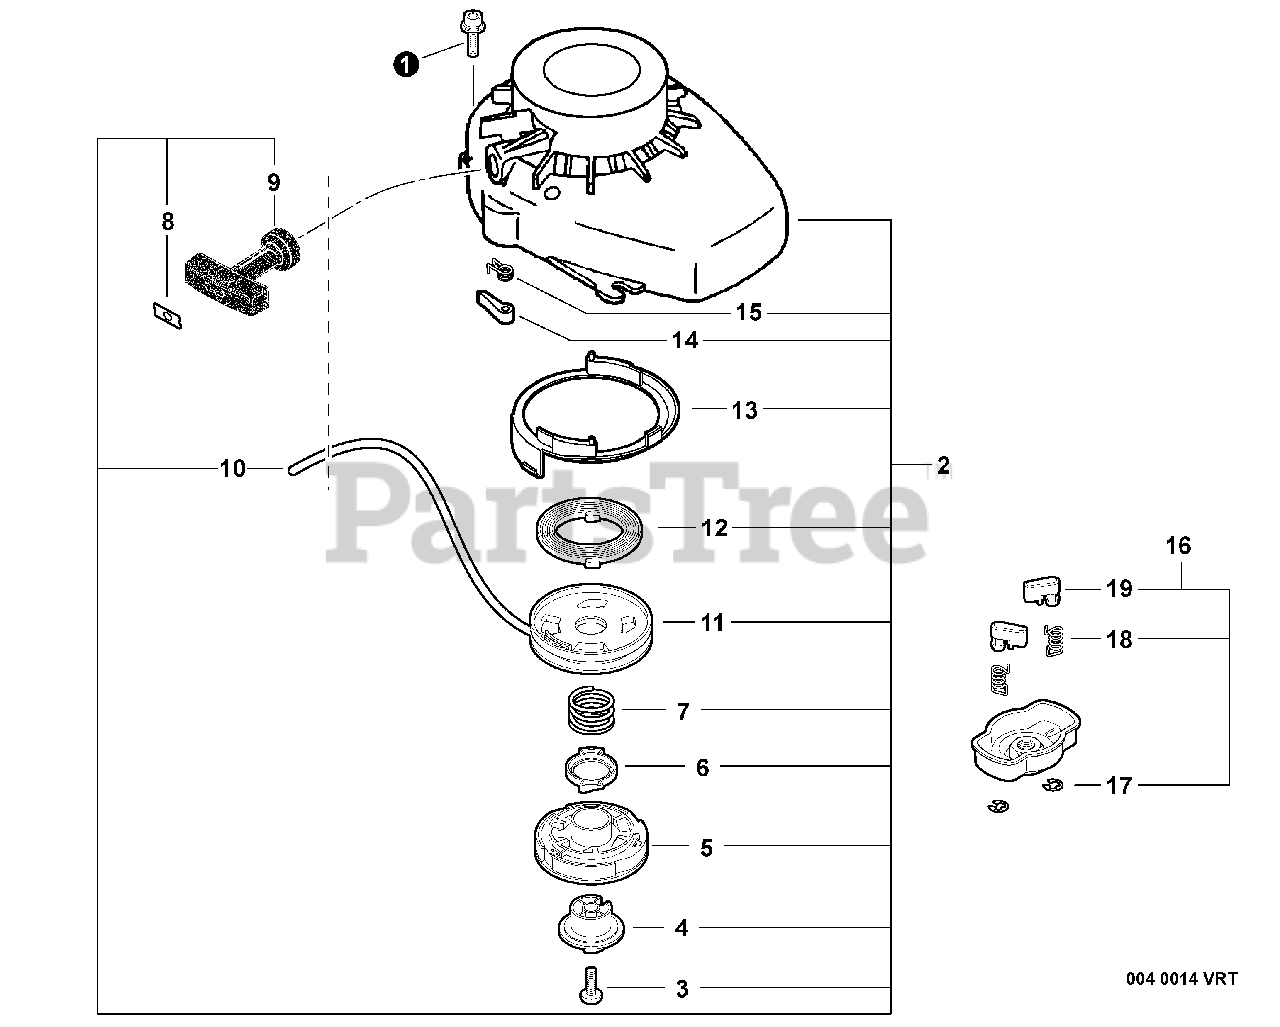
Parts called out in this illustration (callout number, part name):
1	SCREW - 4X16
2	STARTER ASSY - GRAY
4	PLATE, CAM
5	SPRING ASSY
7	SPRING, RETURN
8	RETAINER, ROPE
9	GRIP, STARTER
10	ROPE, STARTER - 3X800
11	REEL, ROPE
12	SPRING, REWIND
13	CASE, STARTER
14	PAWL, STARTER
15	SPRING, PAWL RETURN
16	STARTER PAWL ASSY
17	RING, RETAINING - 4
18	SPRING, RETURN
19	PAWL, STARTER
